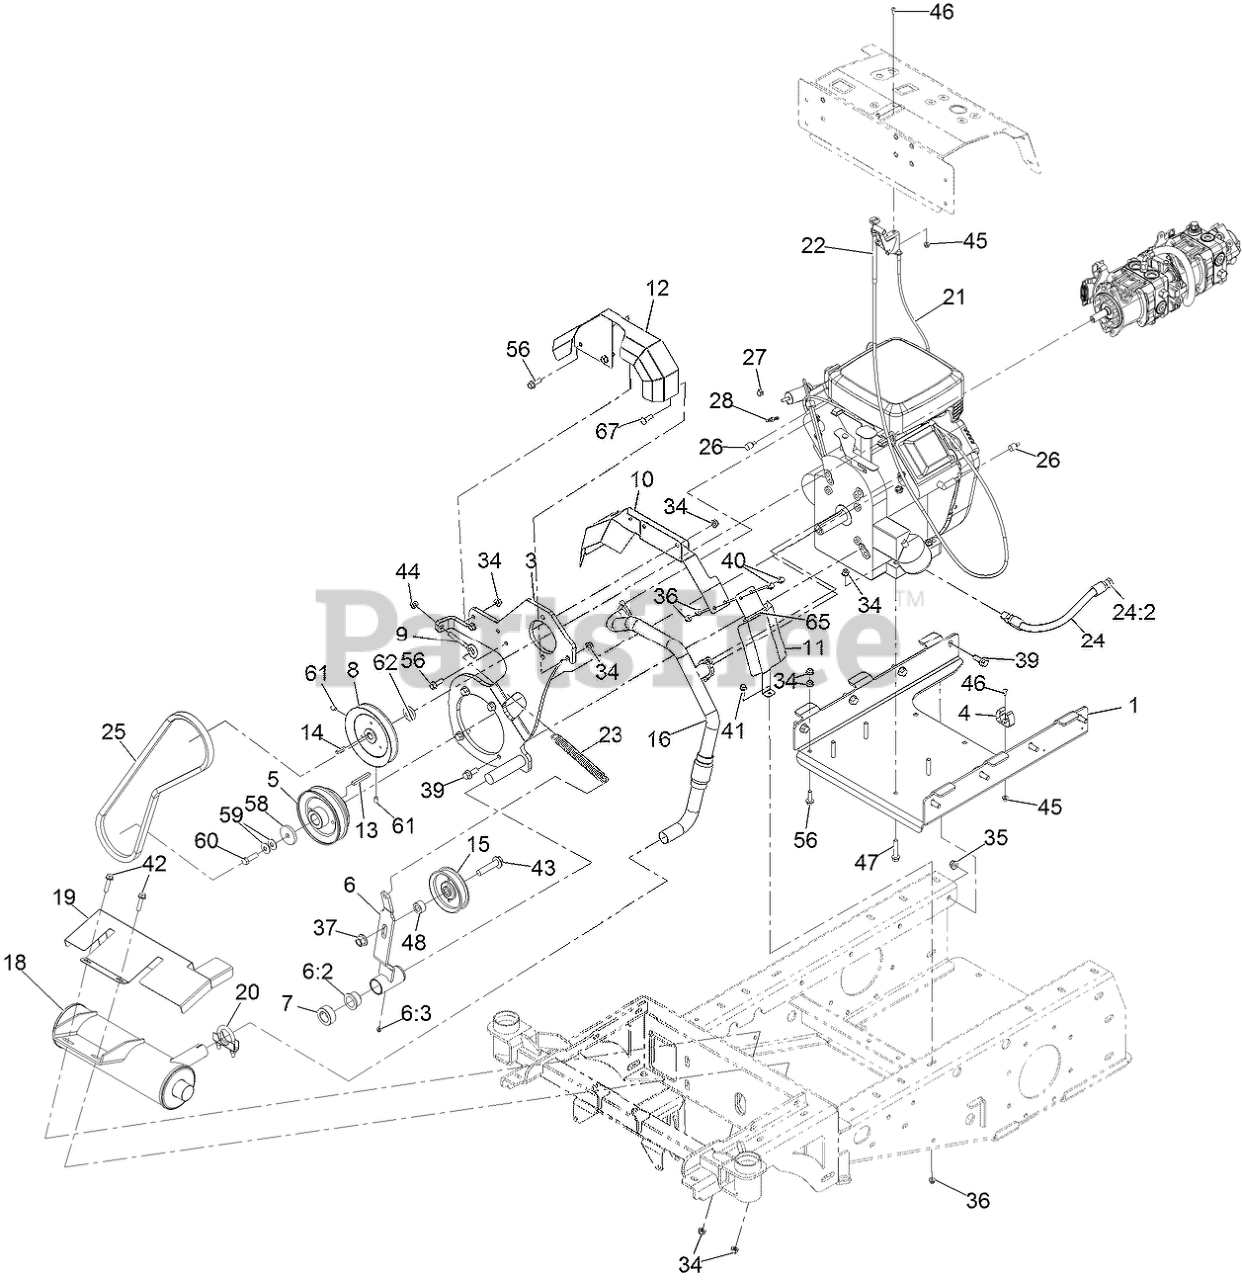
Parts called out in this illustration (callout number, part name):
1	Tray-Engine
3	Bracket-Engine, Pump [black]
4	Holder-Tool, Clip
5	Pulley-Double
6	Arm-Tension, ASM
6:2	BUSHING-FLANGE
6:3	FITTING-GREASE, ZERK
8	PULLEY-DRIVE, PUMP
9	Bolt-Eye
10	Guard, Lower Muffler
11	Guard, Lower Muffler
12	GUARD-PULLEY
15	PULLEY-IDLER, FLAT
16	MANIFOLD-EXHAUST
18	MUFFLER
19	SHIELD-HEAT, MUFFLER
20	Clamp-Muffler
21	CABLE-THROTTLE
22	CABLE-CHOKE
23	SPRING-EXTENSION
24	ASM, Oil Drain Hose W/Plug
26	Tube-Heat Shrink, 1/2
27	CLAMP-HOSE
28	Fitting-STR
34	Nut-Hex Flange
35	Nut-Hex Flange
36	Nut-Hex Flange
37	Nut-Lock 1/2-13
39	SCREW-HHF
40	SCREW-HHF
41	Screw-HHF
42	SCREW-HHF
43	Screw-HHF
44	NUT-HF, NI
45	Nut-Hex Flange
46	Screw-HSBH
47	Screw-HHF
56	SCREW-HHF
58	WASHER-PLAIN
59	WASHER-BELLEVILLE
60	Screw-HH
61	Setscrew-HSH
65	TIE-CABLE
67	Bolt,Carriage,5/16-18X1,ST/ST 18-8
